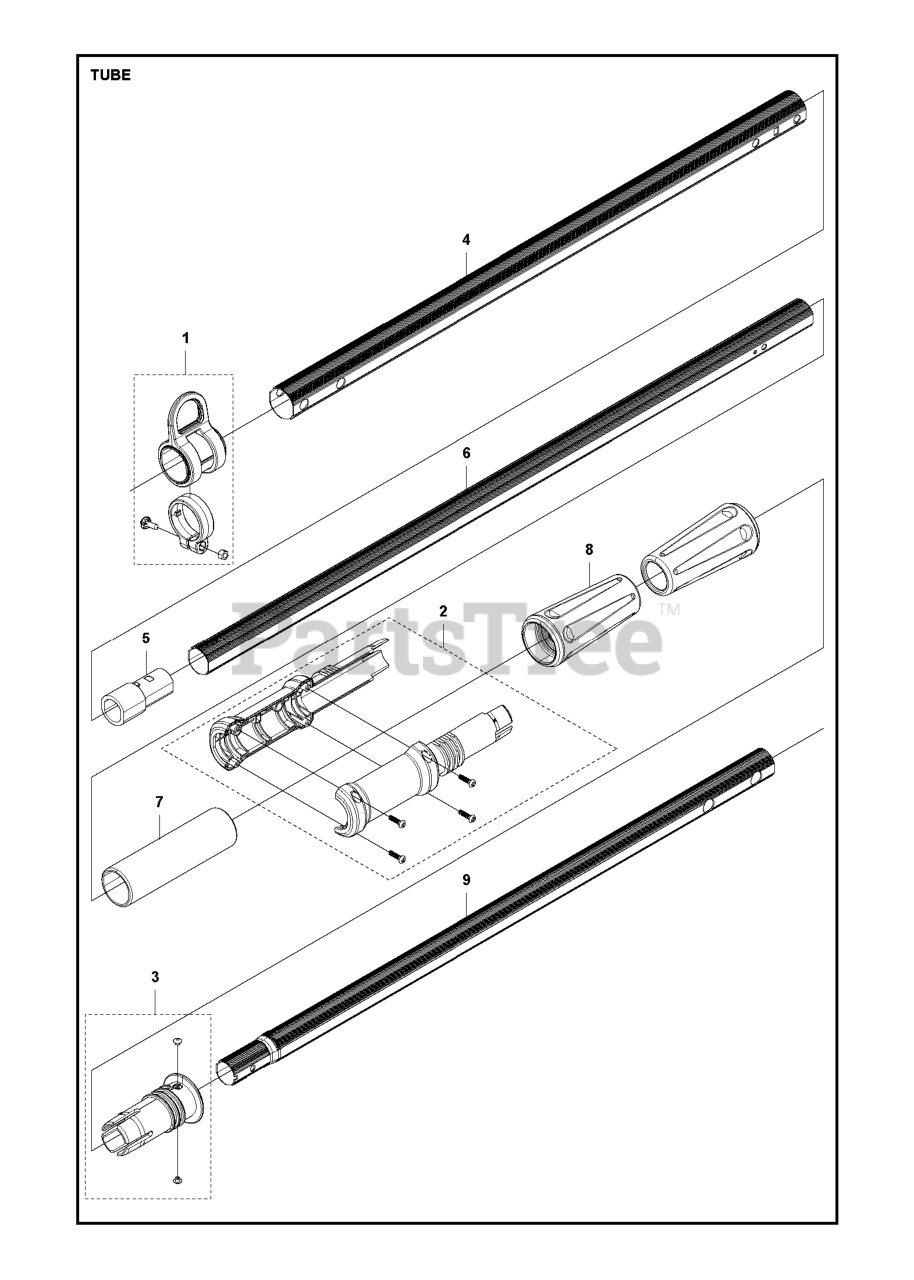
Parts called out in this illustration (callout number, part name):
1	HOOK HARNESS SUPPORT
2	COVER ASSY CONNECT
3	HOLDER ASSY
5	EXTENSION JOINT STOPPER
6	TUBE EXTENSION
